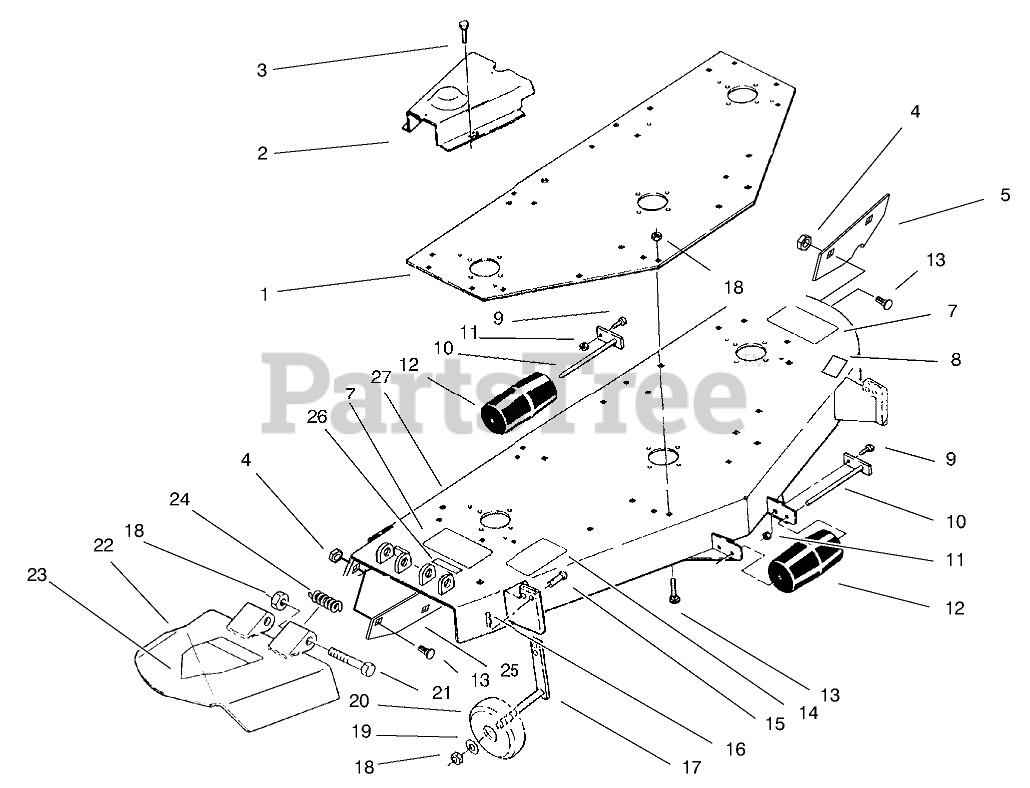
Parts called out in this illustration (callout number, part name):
1	PLATE-TOP REINFOR R
2	Belt Cover
3	SCREW-HWH, TAPTITE
4	NUT-LOCK, NI
5	PLTE WEAR LH
6	BOLT-CARR
7	DECAL-DANGER
8	DECAL - WHEEL ADJUSTMENT
9	BOLT-CARR
10	ROLLER-SHAFT
11	NUT-LOCK, NI
12	ROLLER-ANTI SCALP
13	BOLT-CARR
14	DECAL-BELT INSTALL
15	PIN-CLEVIS 3/8 X 1
16	PIN-HAIR
17	GAGE-WHEEL
18	NUT-LOCK, NI
19	WASHER-FLAT
20	WHEEL-GAGE
21	SCREW-HH
22	Chute Guard Assembly (Incl. Ref.# 23)
23	DECAL-DANGER
24	SPRING
25	Wear Plate RH
26	DECAL-CAUTION
27	Deck (Incl. Ref. #7 & 26)
